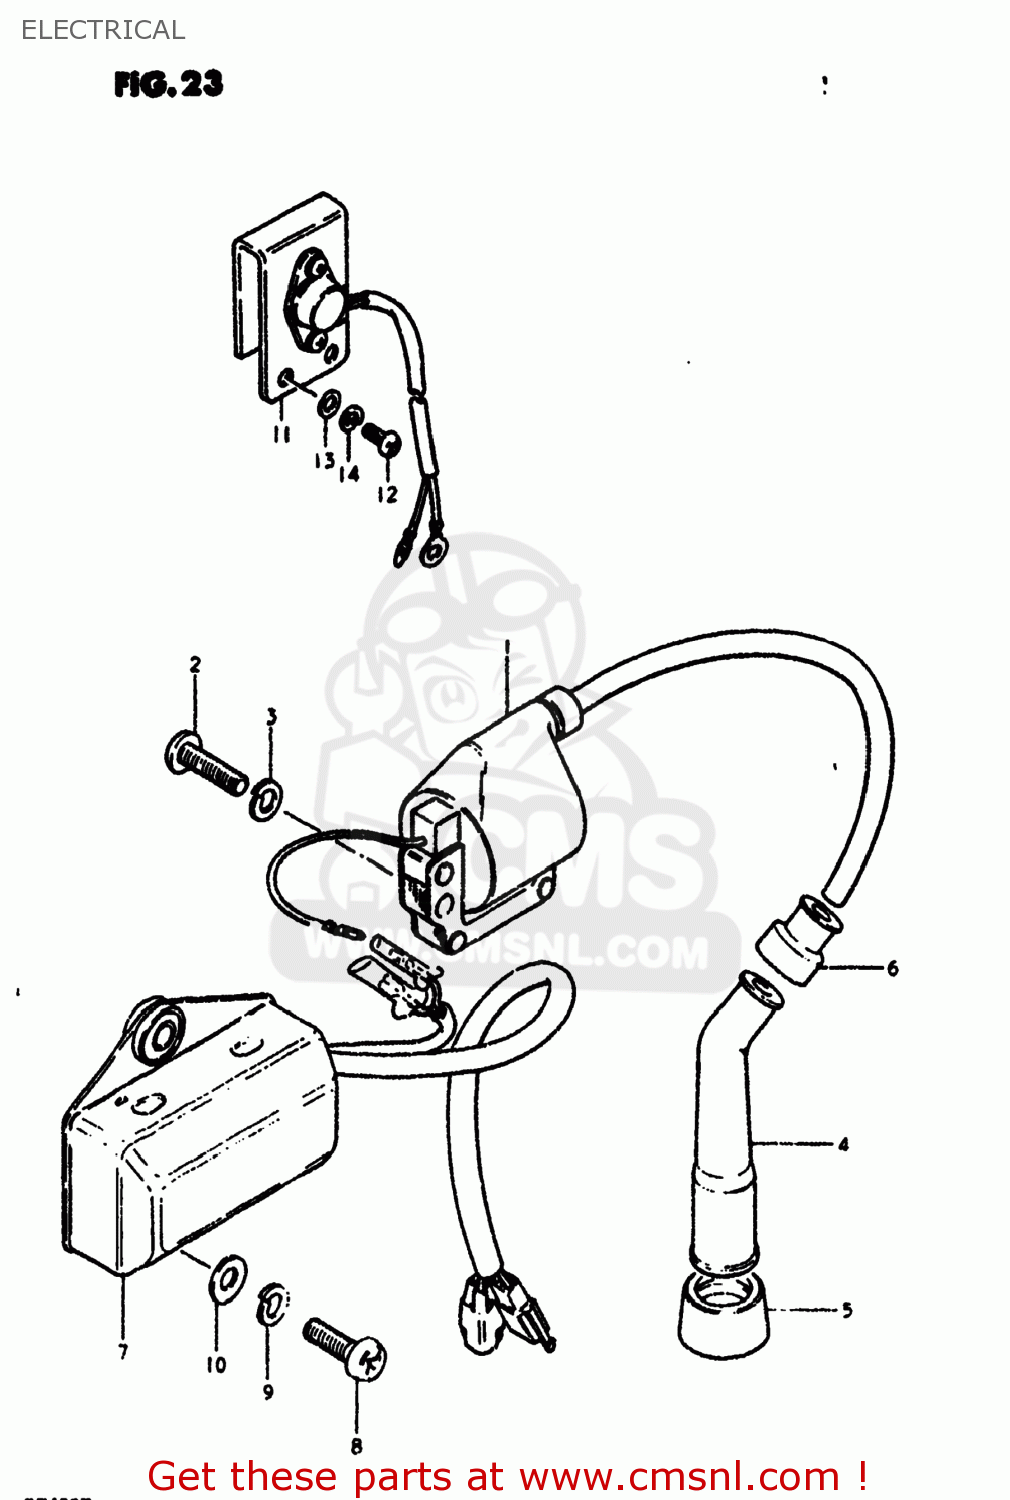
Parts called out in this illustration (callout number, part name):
1	COIL ASSEMBLY,IGNITION
2	SCREW
3	LOCK WASHER
4	CAP ASSY,SPARK PLUG
5	SEAL,SPARK PLUG
6	SEAL,SPARK PLU
7	CDI UNIT
8	SCREW, 6X20
9	LOCK WASHER
10	WASHER
11	REGULATOR ASSEMBLY
12	SCREW
13	WASHER
14	LOCK WASHER
